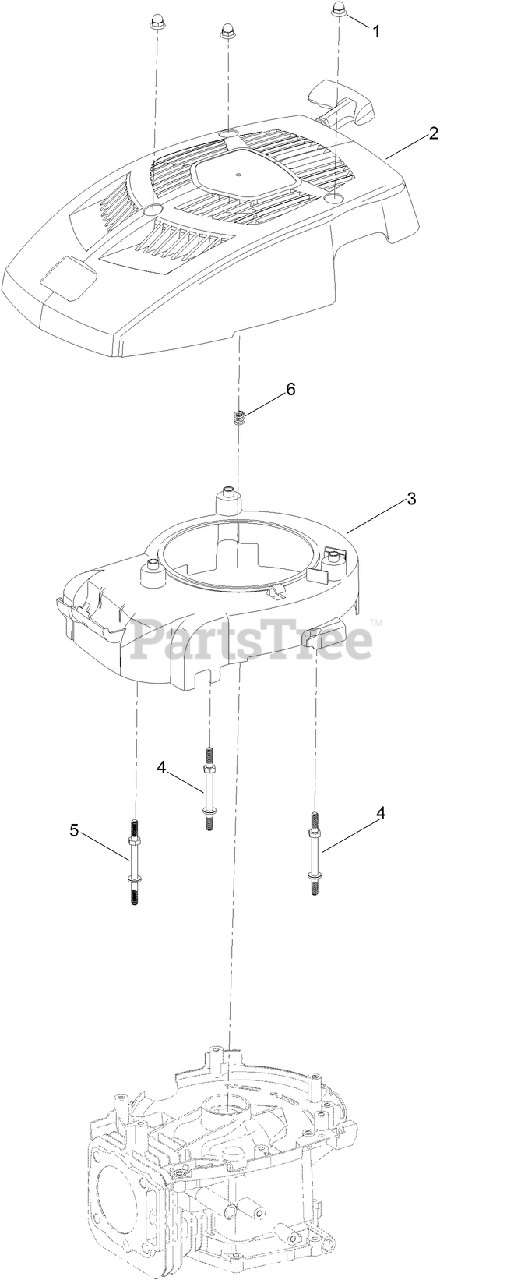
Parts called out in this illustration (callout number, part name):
1	NUT-ACORN
2	RECOIL SHROUD ASM
3	SHROUD-FAN
4	STUD-SHROUD
5	STUD-SHROUD
6	SPRING-COMPRESSION, RECOIL
